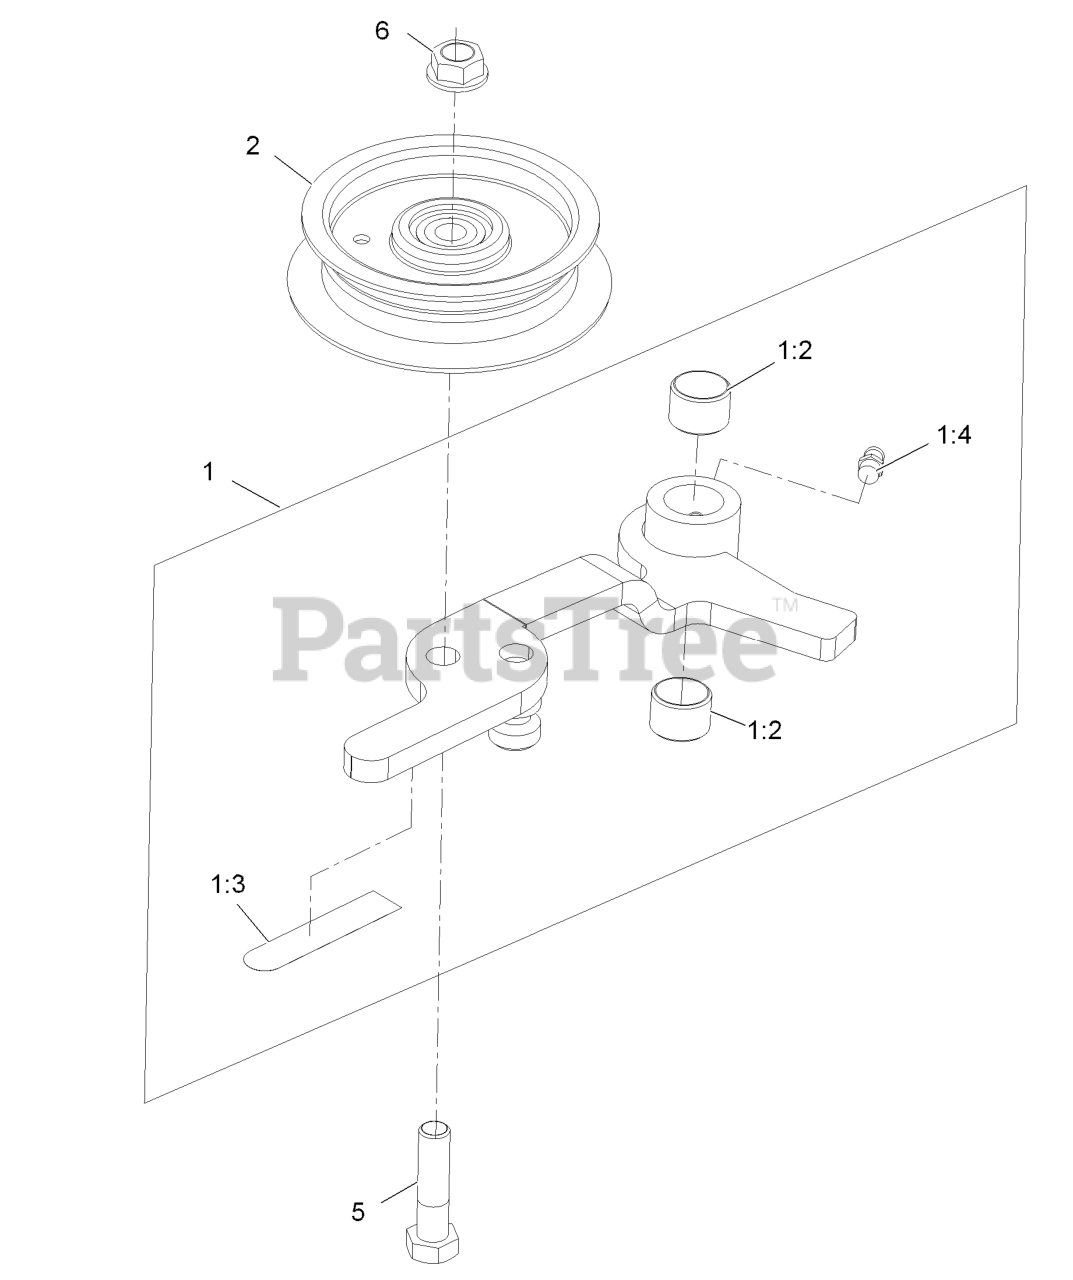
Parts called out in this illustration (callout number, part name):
1	ASM, IDLER ARM - SERVICE
1:2	BUSHING
1:3	DECAL-WARNING
1:4	FITTING-GREASE
2	IDLER-FLAT
5	SCREW-HH
6	NUT-HHF, WHIZ
